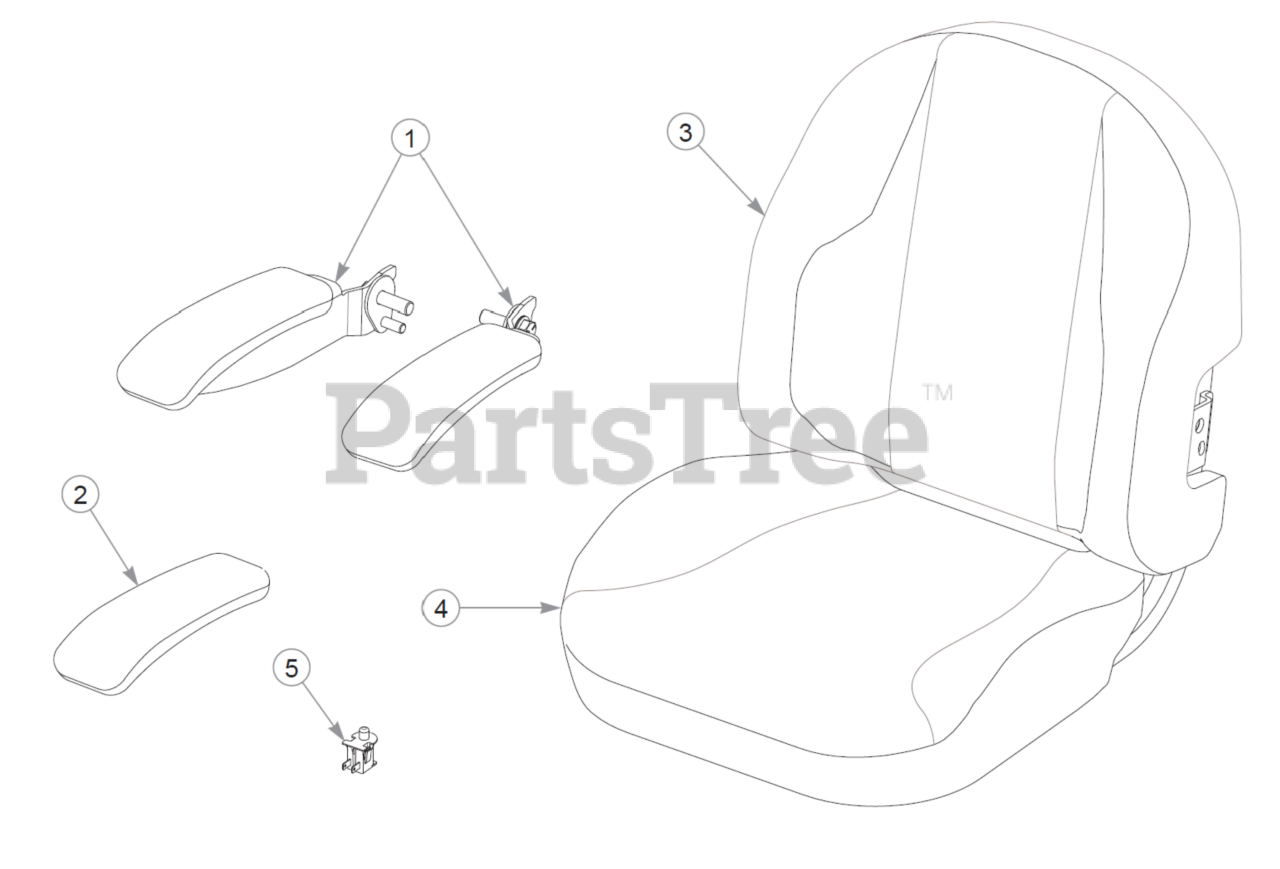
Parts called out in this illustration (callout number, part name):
1	SVC, ARM REST KIT
2	SVC, ARM PAD
3	SVC, SEAT BACK COVER
4	SVC, SEAT CUSHION COVER
5	SVC, OPS
